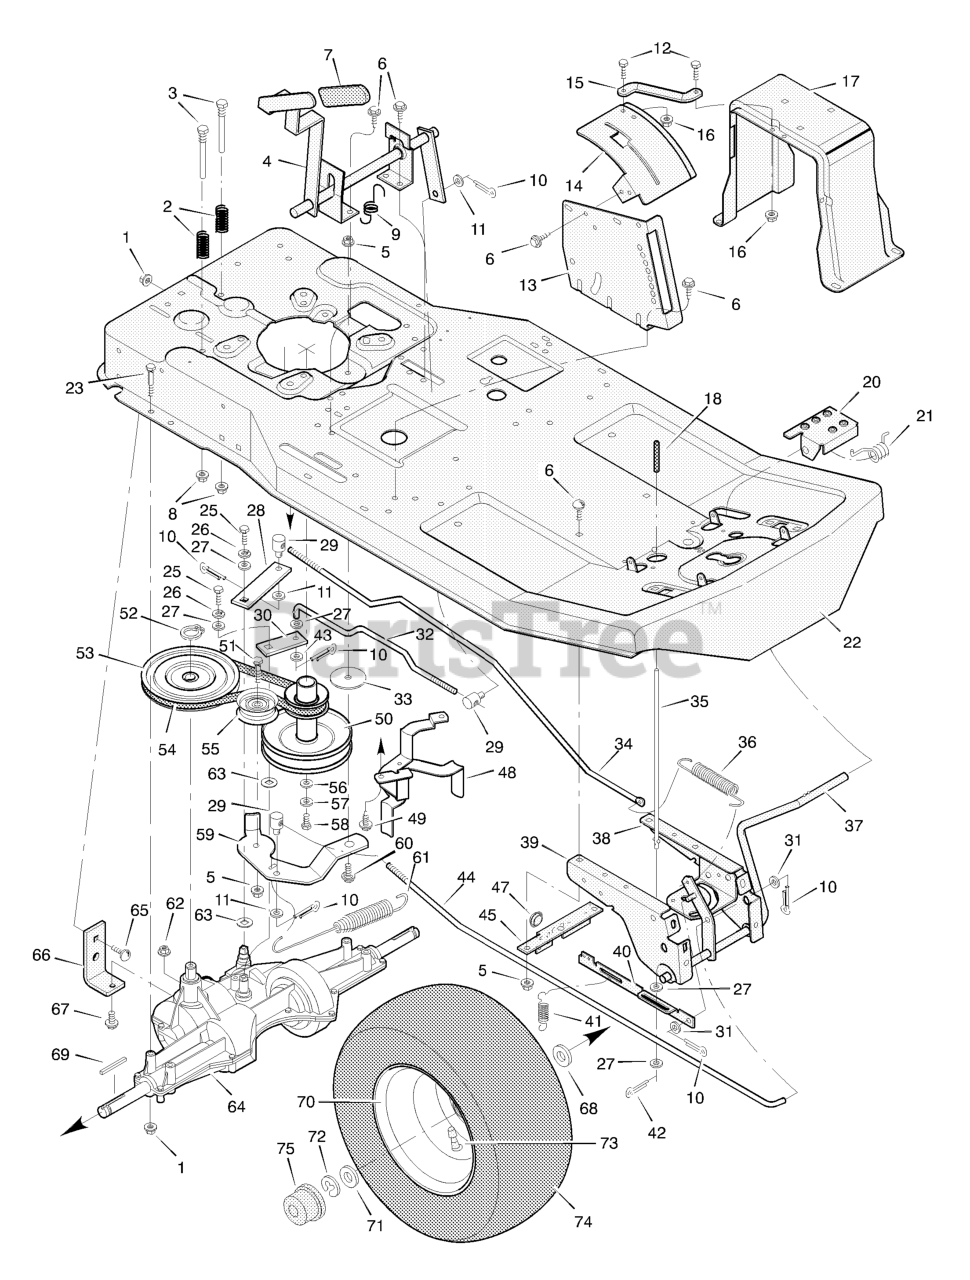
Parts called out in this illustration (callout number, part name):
1	Locknut, Flange
2	Spring, Compression
3	Guide, Belt
4	Shifter Assembly
5	Locknut, Flange
7	Grip, Shift Lever
8	Hex Nut
9	Spring, Extension
10	Pin, Cotter
12	Bolt, Hex
13	Plate, Index
14	Gate, Shift
15	Brace, Shift Gate
16	Locknut, Flange
17	Support, Seat
18	Grip, Parking Brake
22	Frame Assembly
23	Bolt, Hex
25	Bolt, Hex
26	Lockwasher
28	Yoke, Brake
29	Nut, Adjusting
30	Yoke, Shift
31	Washer
32	Rod, Shift
33	Washer, Hardened
34	Rod, Brake
35	Rod, Parking Brake
36	Spring, Extension
37	Lever, Pedal
38	Plate, Left Suspension
39	Plate, Right Suspension
40	Link, Parking Brake
41	Spring, Extension
42	Pin, Cotter
44	Rod, Clutch
45	Stop, Parking Brake
47	Grommet
48	Guide, Belt
50	Pulley Assembly, Stack
51	Bolt, Hex
52	Ring, Retainer
53	Pulley, Drive
54	Belt, Motion Drive
55	Pulley, Idler
57	Lockwasher
58	Bolt, Hex
59	Bracket, Idler
60	Bolt, Shoulder
61	Spring, Extension
62	Locknut, Hex
64	Transaxle, Dana Model 4450-1 **
65	Bolt, Carriage
66	Bracket, Transaxle
67	Bolt, Hex
69	Key, Square
70	Wheel & Tire Assembly
73	Valve Stem
74	Tire *
75	Hub Cap
